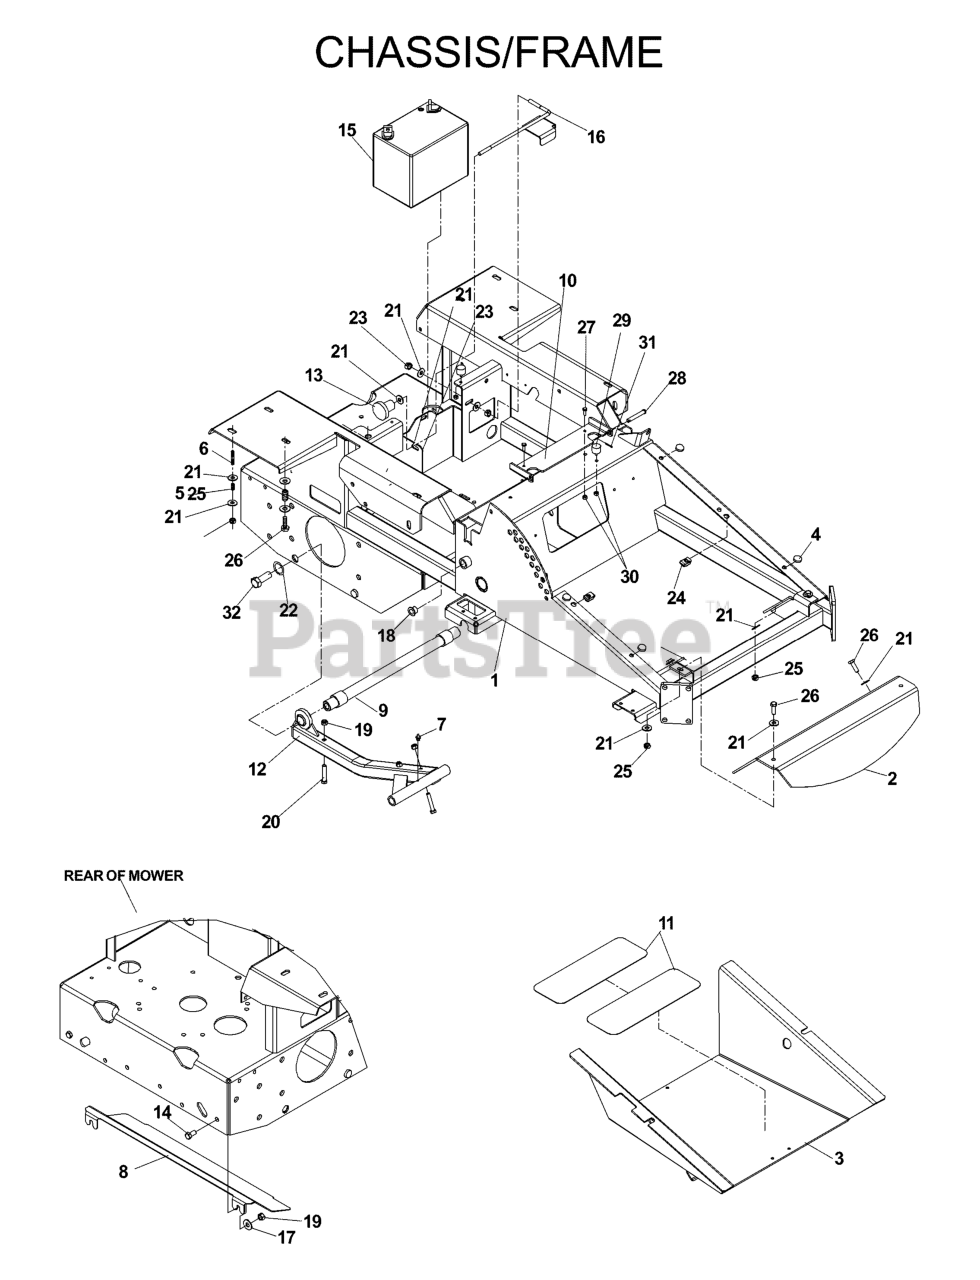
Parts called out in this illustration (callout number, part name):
1	CHASSIS W/DECALS
2	FOOTREST ORANGE
3	IZ FOOTPLATE W/DECAL
4	GROMMET, BUMPER
6	STUD, 5/16C
7	ZERK
8	REAR GUARD
9	STRUT MOUNT WELDMENT
10	SEAT BRKT W/DECAL
11	ANTI-SKID PAD
12	STRUT, RIGHT
14	SCREW 3/8C X 3/4 HEX CAP
15	BATTERY, 12 V 330 AMP
16	BATTERY HOLD DOWN
17	WASHER 3/8 FLAT
19	NUT 3/8-16 NYLOC
20	HCS 3/8C X 2
21	WASHER 5/16 FLAT
22	LOCKWASHER 5/8
23	NUT 5/16C CENTERLOCK
24	U-CLIP 5/16-18 NUT RETAINER
25	NUT 5/16 NYLOC
26	HCS 5/16C X 1
27	HCS 1/4C X 3/4 HCS
28	CLEVIS PIN 3/8
29	STUD/PLATE MOUNT
30	NUT.1/4-20.HEX.NYLOC.ZD
31	RP_COTTER PIN 1/8 X 3/4
32	HCS 5/8C X 2 GR.5
